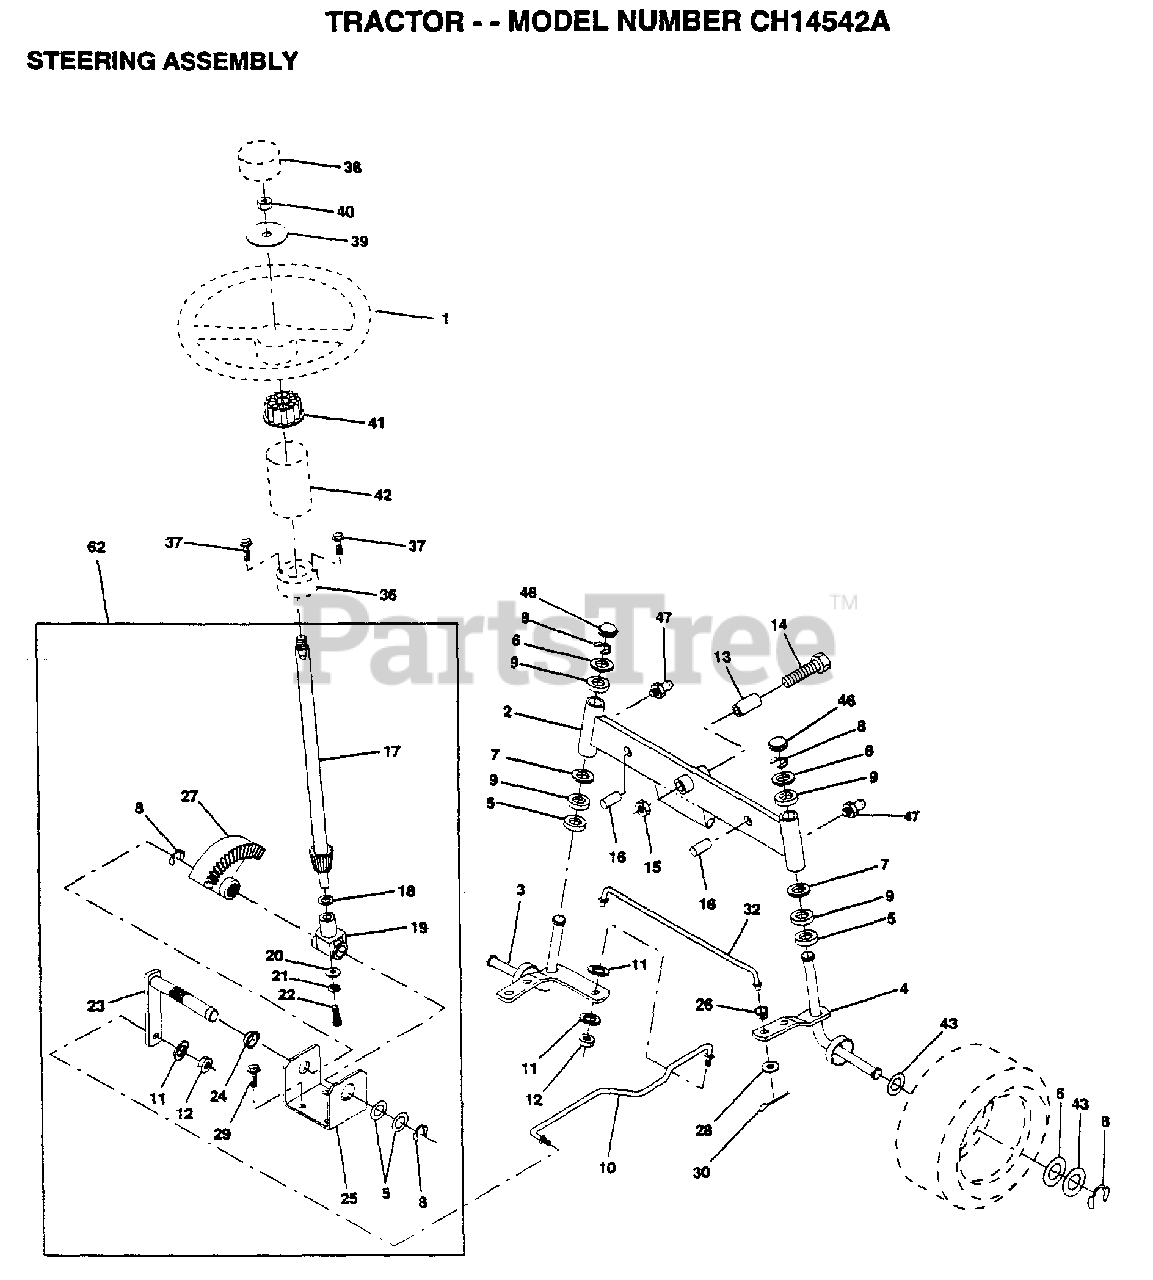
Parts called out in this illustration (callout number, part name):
2	AXLE ASM FRONT
3	SPINDLE LH
4	SPINDLE RH
5	WASHER .T
6	WASHER
7	WASHER
8	RING
9	COL. SRTG. BEAR.
11	LOCKWASHER
13	BEARING
14	BOLT HEX 5/8-11
15	"NUT-LOC,FLANGE LT"
16	AXLE PIN
17	SHAFT ASM
18	THRUST WASHER
19	SUPPORT.SHAFT
21	LOCKWASHER
22	"SCREW,SPECIAL"
24	NYLINER T
25	"BRKT,STEERING"
26	BUSHING.DRAGLINK
27	GEAR SECTOR
28	WASHER
29	SCREW
30	COTTER PIN
32	TIE ROD
38	ST WHL INSERT CAP
39	WASHER T
40	GRIPCO NUT
41	ADAPTER-WHEEL LT
42	"TUBE, STR SHAFT"
43	WASHER
46	CAP
47	ZERK M
